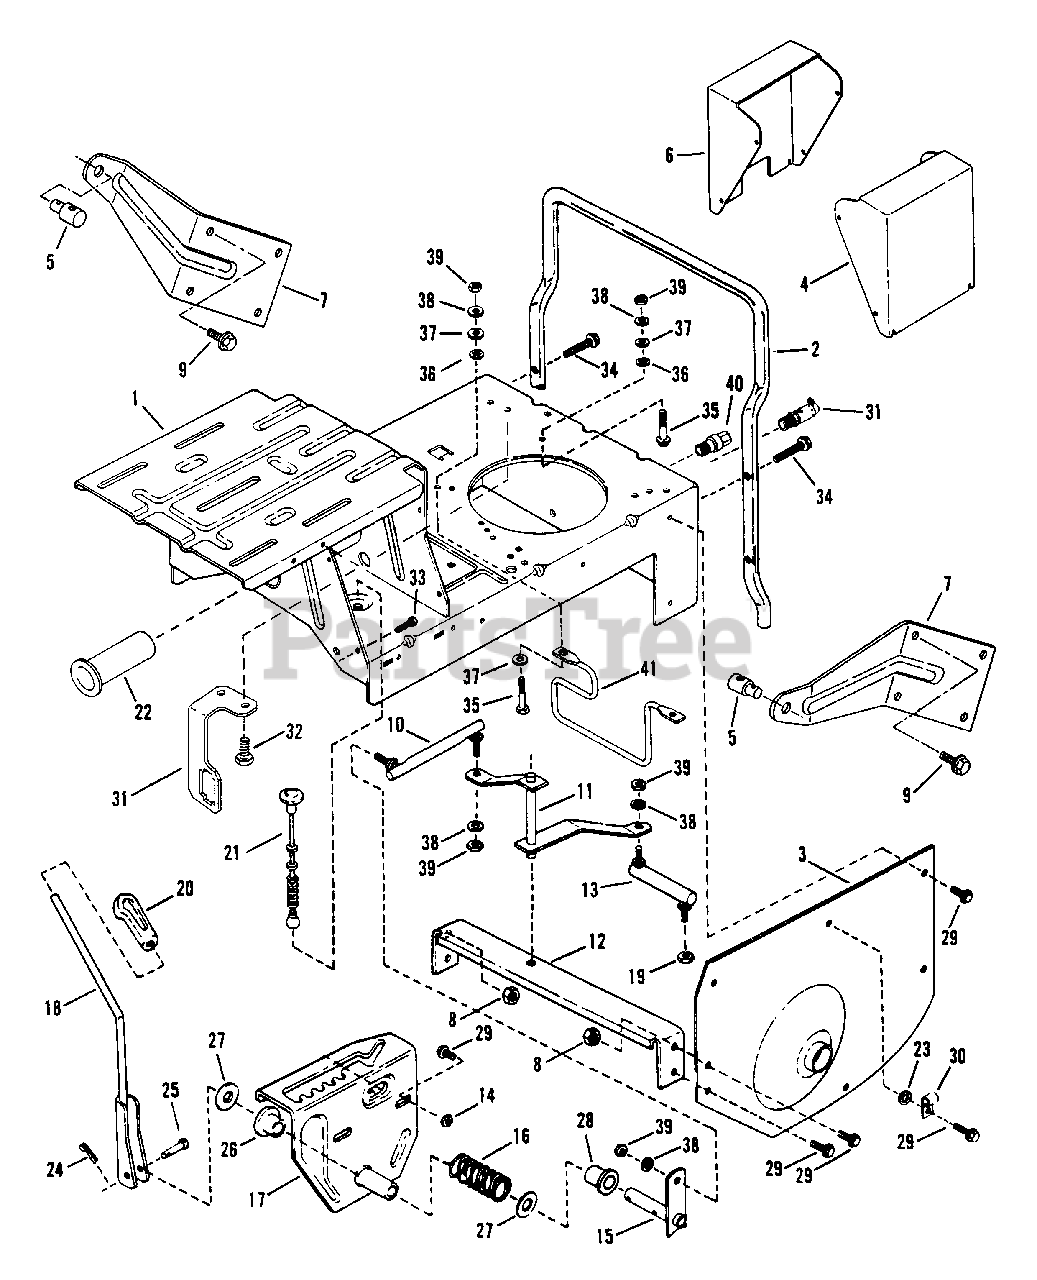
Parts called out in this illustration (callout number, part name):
1	CASE, Main
2	BUMPER, Rear
3	FENDER, Left Hand
4	COVER, Battery
5	SWIVEL
6	COVER, Switch
7	WING, Rear
8	NUT, 5/16-18 Hex Flange Lock
9	SCREW, 5/16-18 x 3/4" Self-Tapping
10	LINK, Shift (Long)
11	ARM, Shift
12	BRACE, Cross
13	LINK, Shift (Short)
14	NUT, 5/16-18 Hex
15	ARM, Shift Handle
16	SPRING, Shift Handle
17	DETENT, Shift
18	HANDLE, Shift
19	NUT, Flange Lock 5/16-24
20	KNOB, Shift Handle
21	CABLE, Deck Support
22	BUSHING, Pilot
23	WASHER, 5/16 Internal Tooth Lock
24	PIN, 3/32 x 3/4" Cotter Hair
25	PIN, 1/4 x 1-3/4" Tapered Clevis
26	BUSHING, Nylon
27	WASHER, Thrust
28	BUSHING, Nylon
29	SCREW, 5/16-18 x 5/8" Self-Tapping
30	CLIP, Wire
31	BRACKET, Switch
32	SCREW, Self Tapping, 10-32 x 1/4
33	FASTENER, 1/4 x 3/4 Ratchet
34	SCREW, 5/16-18 x 1-1/2" Self-Tapping
35	SCREW, 5/16-24 x 1-3/4" Hex Head Cap
36	RETAINER, 5/16 Bolt
37	WASHER, 5/16" Flat
38	WASHER, 5/16" Split Lock
39	NUT, 5/16-24 Hex
40	DRAIN, Oil (Short)
41	GUIDE, Belt
